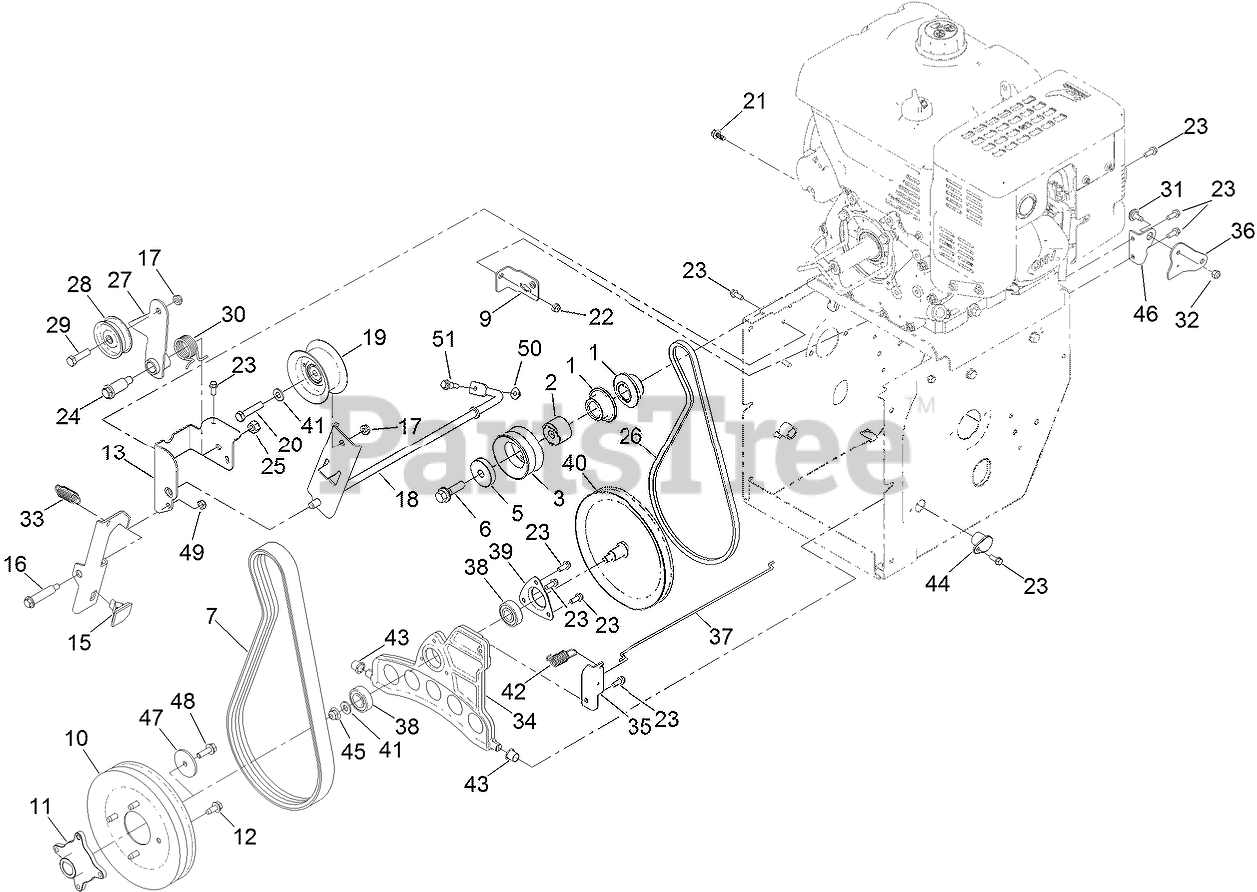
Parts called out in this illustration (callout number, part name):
1	PULLEY-TRACTION, ENGINE
2	PULLEY-SPACER
3	PULLEY-IMPELLER, DOUBLE SHEAVE
5	SUPPORT-PULLEY
6	BOLT-BLADE
7	BELT-V
9	BRACKET-CLUTCH, IMPELLER
10	PULLEY-IMPELLER, DOUBLE SHEAVE
11	HUB-PULLEY
12	SCREW-HWHTF
13	BRACKET-BRAKE, CLUTCH
15	PAD-BRAKE
16	BOLT-SHOULDER
17	NUT-HEX
18	ARM-CLUTCH, IMPELLER
19	PULLEY, IDLER
20	SCREW-HH
21	SCREW-HHF
22	NUT-HF
23	SCREW-HWH
24	BOLT-SHOULDER
25	NUT-HEX
26	V-BELT
27	ARM-IDLER, TRACTION
28	PULLEY-IDLER
29	SCREW-HH
30	SPRING-TORSION
31	SCREW-SHOULDER
32	NUT-HEX
33	SPRING-EXTENSION
34	PLATE-FRICTION, WHEEL
35	BRACKET-PLATE, TRACTION
36	BELLCRANK-DRIVE
37	LINK-DRIVE
38	BEARING-BALL
39	RETAINER-BEARING
40	PULLEY-TRACTION
41	WASHER-FLAT
42	SPRING-EXTENSION
43	BUSHING-NYLINER
44	BUSHING-PLATE, TRACTION
45	NUT-HF, NI
47	WASHER-PLAIN
48	SCREW-HHF
49	NUT-HEX
50	NUT-HF
51	BOLT-SHOULDER
